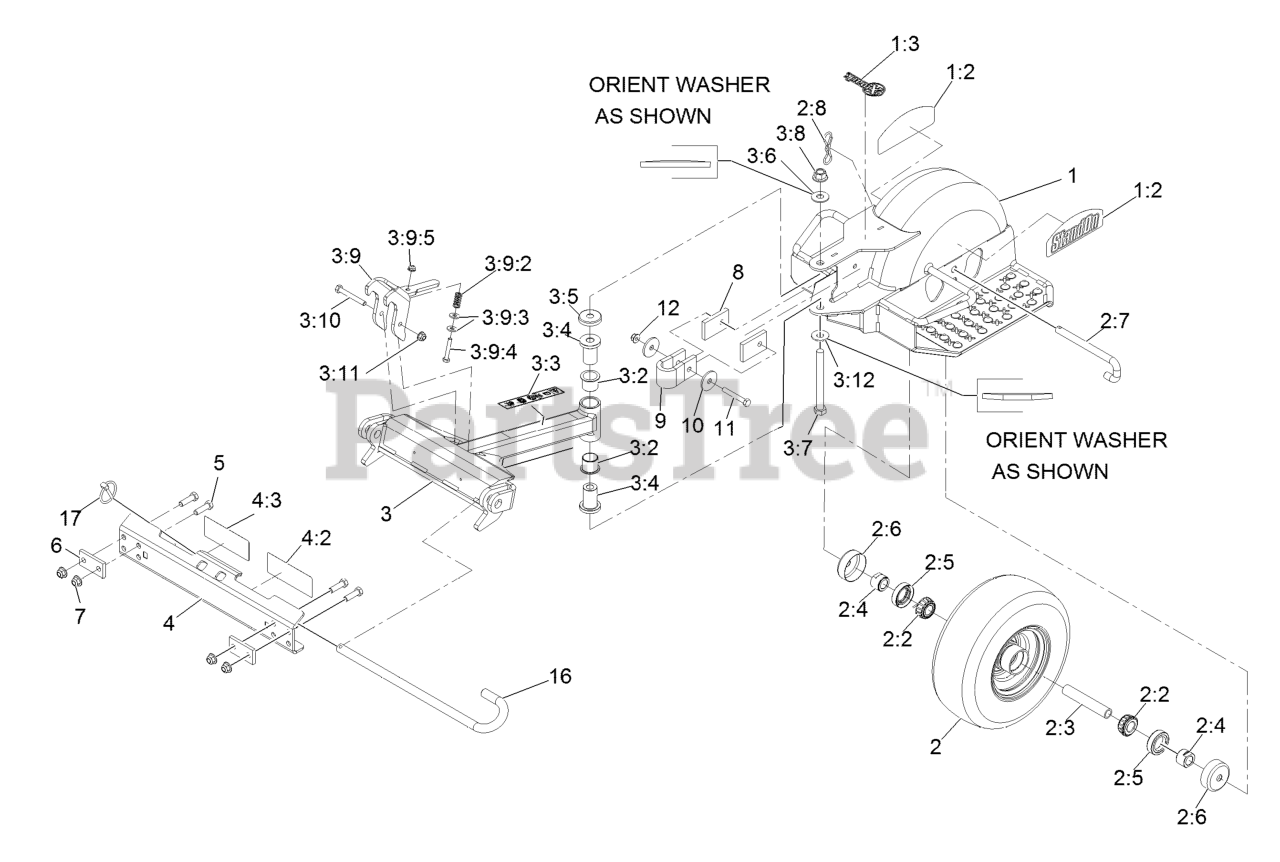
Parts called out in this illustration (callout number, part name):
1	ASM-SULKY FRAME W/ DECALS
1:2	DECAL,STANDON
1:3	DECAL,EXMARK
2	ASM, WHEEL AND BEARINGS
2:2	BEARING-CONE, TAPERED ROLLER
2:4	SPACER-NUT
2:5	SEAL-CASTER
2:6	GUARD-SEAL
2:7	PIN, CASTER
2:8	PIN-COTTER, LOCKING
3	ASM, DRAW BAR
3:2	BUSHING-PIVOT
3:3	DECAL-SULKY HAZARD
3:4	SPACER, PIVOT
3:5	COVER, DUST
3:6	WASHER-BELLEVILLE
3:7	SCREW-HH
3:8	Nut-Lock 1/2-13
3:9	TRANSPORT LATCH ASM
3:9:2	SPRING, COMPRESSION
3:9:3	WASHER-FLAT
3:9:4	SCREW-HH
3:10	SCREW-HH
3:11	NUT-HF, NI
3:12	WASHER-SPRING
4	ASM, MOUNT PLATE
4:2	DECAL-BELT DRIVE WARNING
4:3	DECAL-WARNING, SULKY
5	SCREW-HH
6	PLATE,BACK-UP (PLATED)
7	NUT-HF, NI
8	PAD,STOP
11	SCREW-HH
12	NUT-HF, NI
16	PIN, PIVOT
17	PIN-LYNCH
